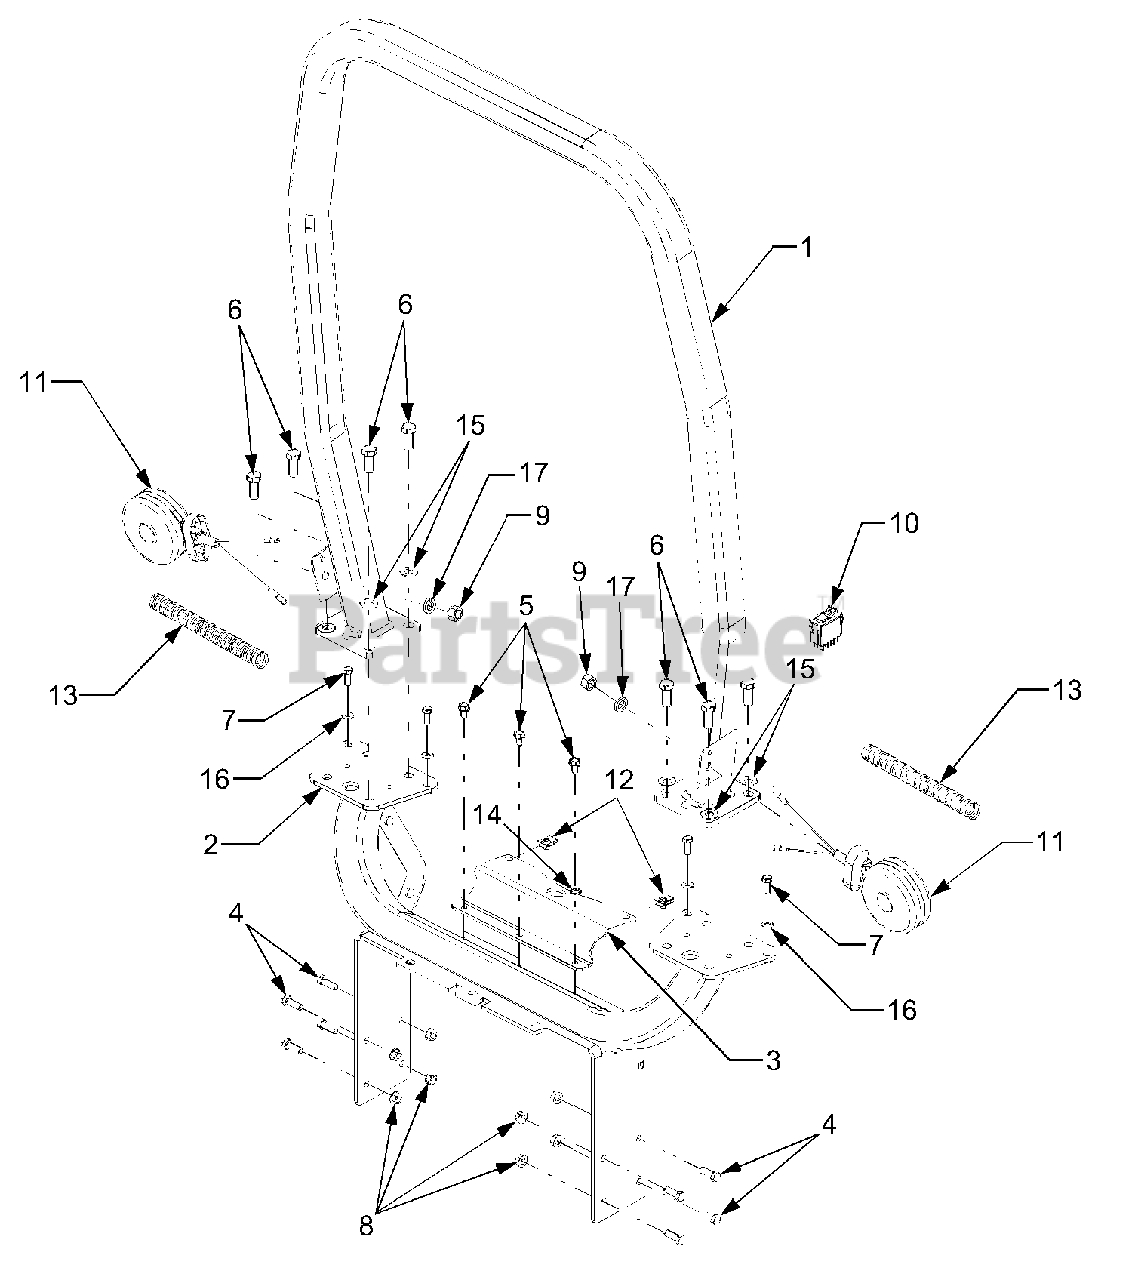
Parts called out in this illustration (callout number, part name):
3	Bracket, Rear Seat Mounting
4	Screw, Hex Cap, 3/8-16 x 1.0 GR5
5	Screw, Hex Wash. Hd. Tapp 5/16-18 x .75
6	Screw, Hex Cap, 1/2-13 x 1.25 GR5
7	Screw, Hex Cap, 5/16-18 x .875 GR5
8	Nut, Hex Flange Lock, 3/8-16 GRF
9	Nut, Hex, 1/2-20 GR5
10	Switch, Hazard
11	Light, Hazard
12	Nut, Speed, 5/16-18
13	Conduit, 6"
14	Washer, Ext. Tooth Lock, 3/8
15	Washer, Flat, .51 x 1.0 x .060
16	Washer, Flat, .344 x .688 x .065
17	Washer, Lock, 1/2
